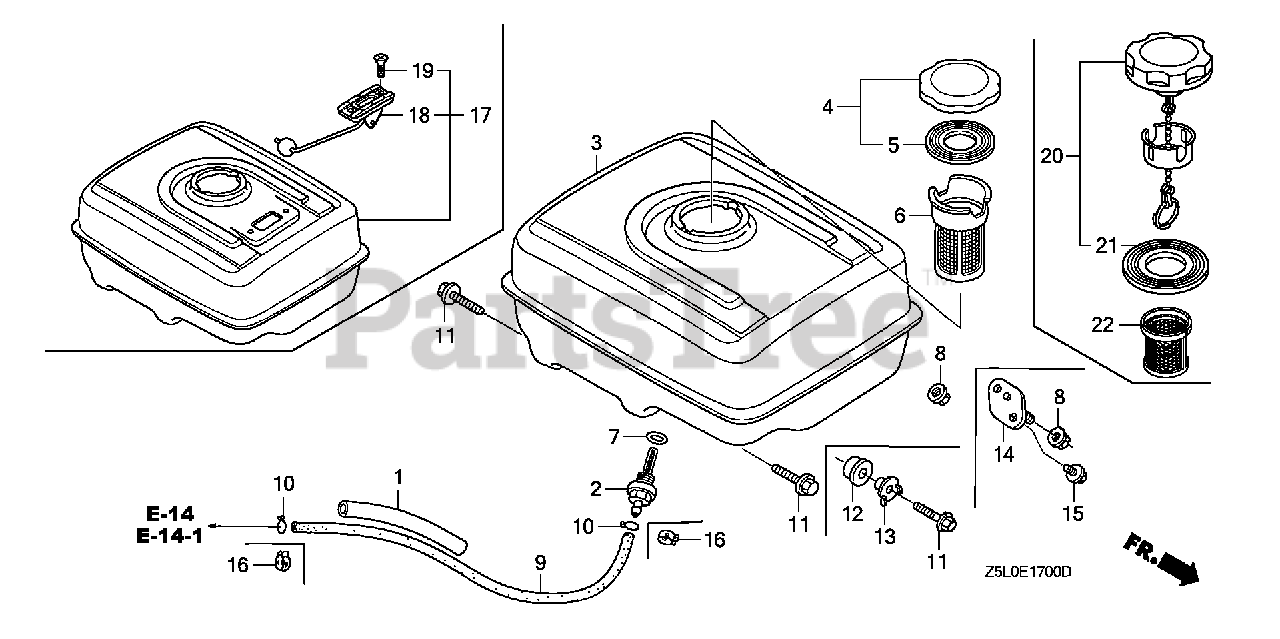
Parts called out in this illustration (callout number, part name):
1	RUBBER, SUPPORTER (107MM)
2	JOINT, FUEL TANK
3	TANK, FUEL *NH1* (BLACK)
3	TANK, FUEL *NH31* (MCKINLEY WHITE)
7	O-RING (14MM) (ARAI) Use up to Engine SN 2949254.
7	O-RING (14MM) (NOK)
8	NUT, FLANGE (8MM)
9	TUBE, FUEL (4.5X235) (FKM)
11	BOLT, FLANGE (8X25)
16	CLIP, TUBE (D8)
20	CAP, FUEL FILLER
21	GASKET, FUEL FILLER CAP
22	FILTER, FUEL (FROM 1204807)
